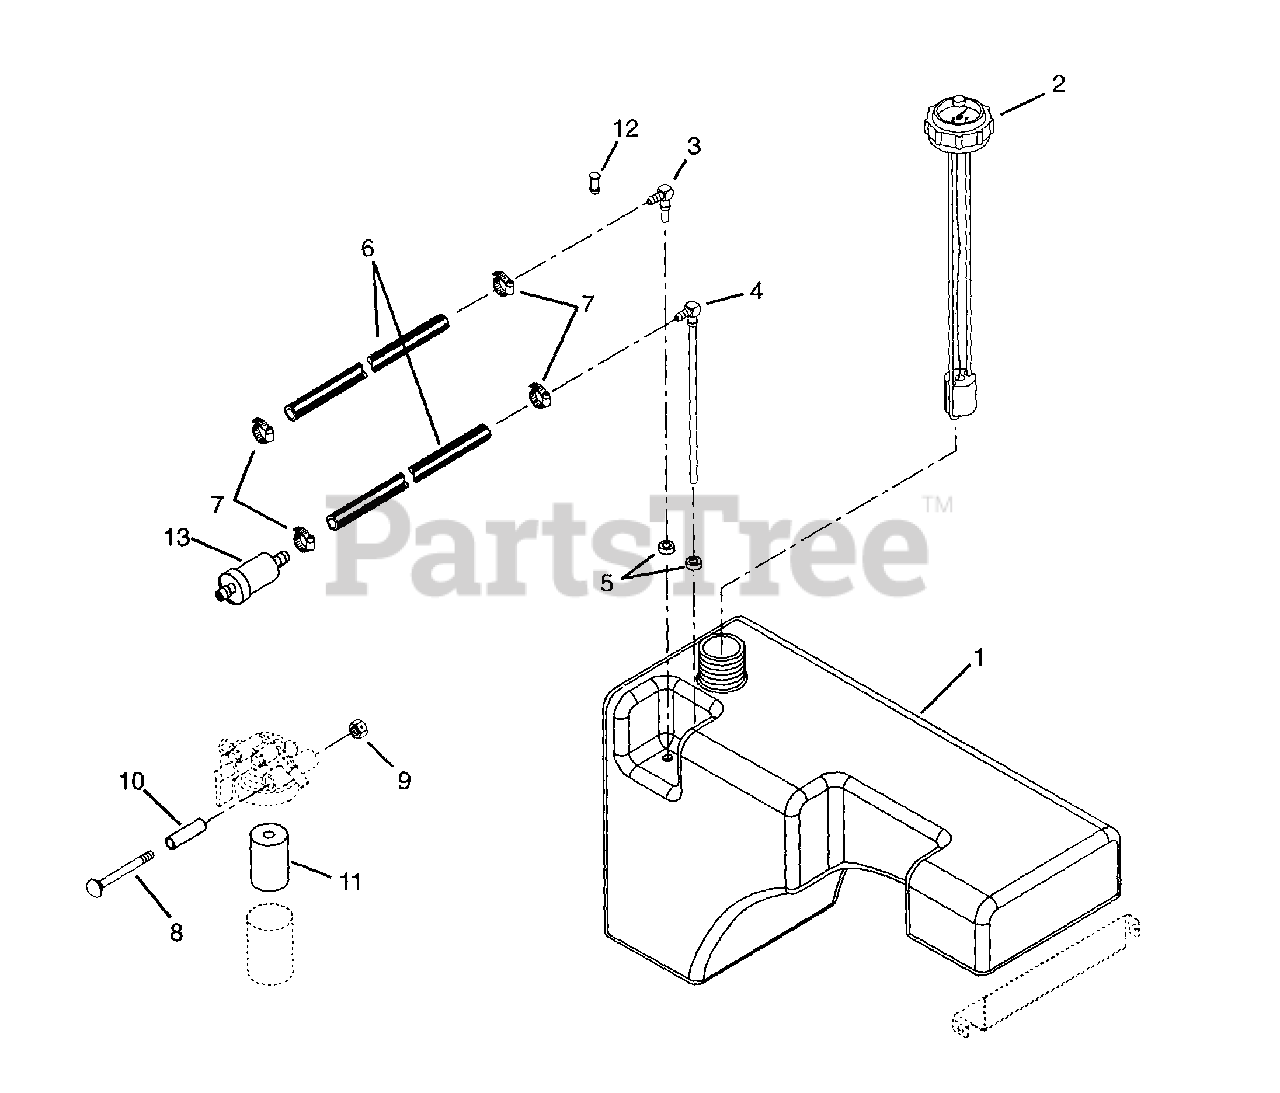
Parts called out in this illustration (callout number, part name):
1	Tank, Fuel
2	Gauge, Fuel
3	Fitting-Tank 1.37 x .406
4	Fitting, Tank
6	Gas Line
7	Hose Clamp
8	Bolt-Round Head Square Neck .31-18 x 3.25
9	Nut-Locking-Center .31-18
10	Bushing-Sleeve .407 x .625 x .750
11	Element, Fuel
12	Plug, Fuel Tank Bushing
13	Filter, Fuel
